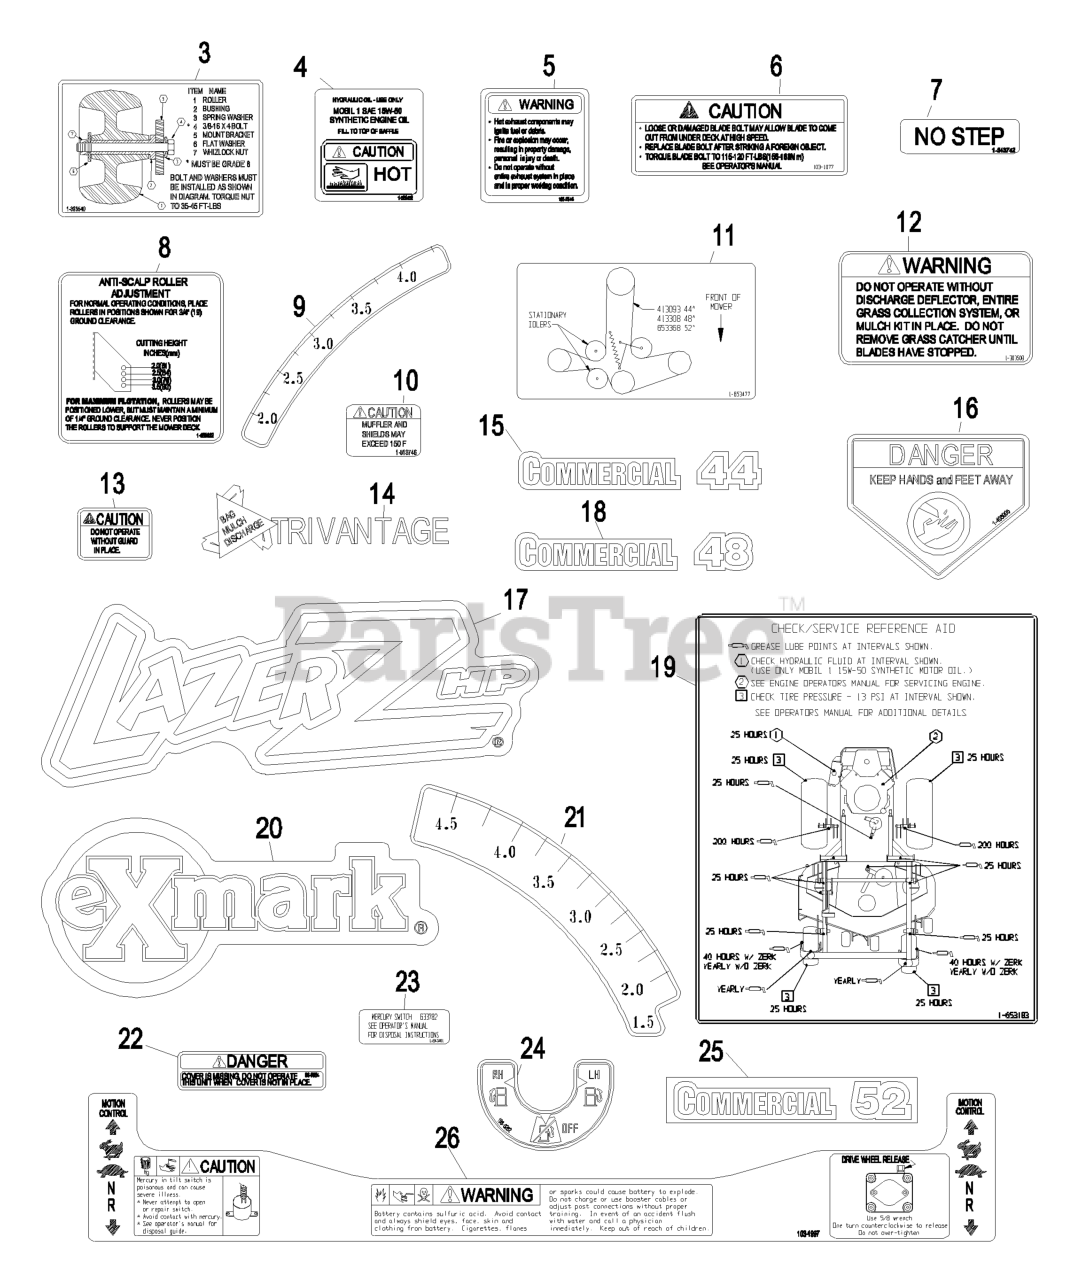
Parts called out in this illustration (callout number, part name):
3	DECAL,ROLLER MOUNTING
5	DECAL-EXHAUST
6	DECAL,BOLT TORQUE
7	DECAL,NO STEP
8	DECAL,ANTISCALP
9	DECAL-DECK HEIGHT, INNER
12	DECAL-WARNING, DISCHARGE
13	DECAL-GUARD
15	DECAL,COMMERCIAL 44
16	DECAL-DANGER
17	DECAL,LHP MODEL
18	DECAL,COMMERCIAL 48
20	DECAL,EXMARK LOGO
21	DECAL-DECK HEIGHT, OUTER
22	DECAL-COVER, MISSING
23	DECAL-SWITCH, MERCURY
24	DECAL-VALVE, FUEL
25	DECAL,COMMERCIAL 52
